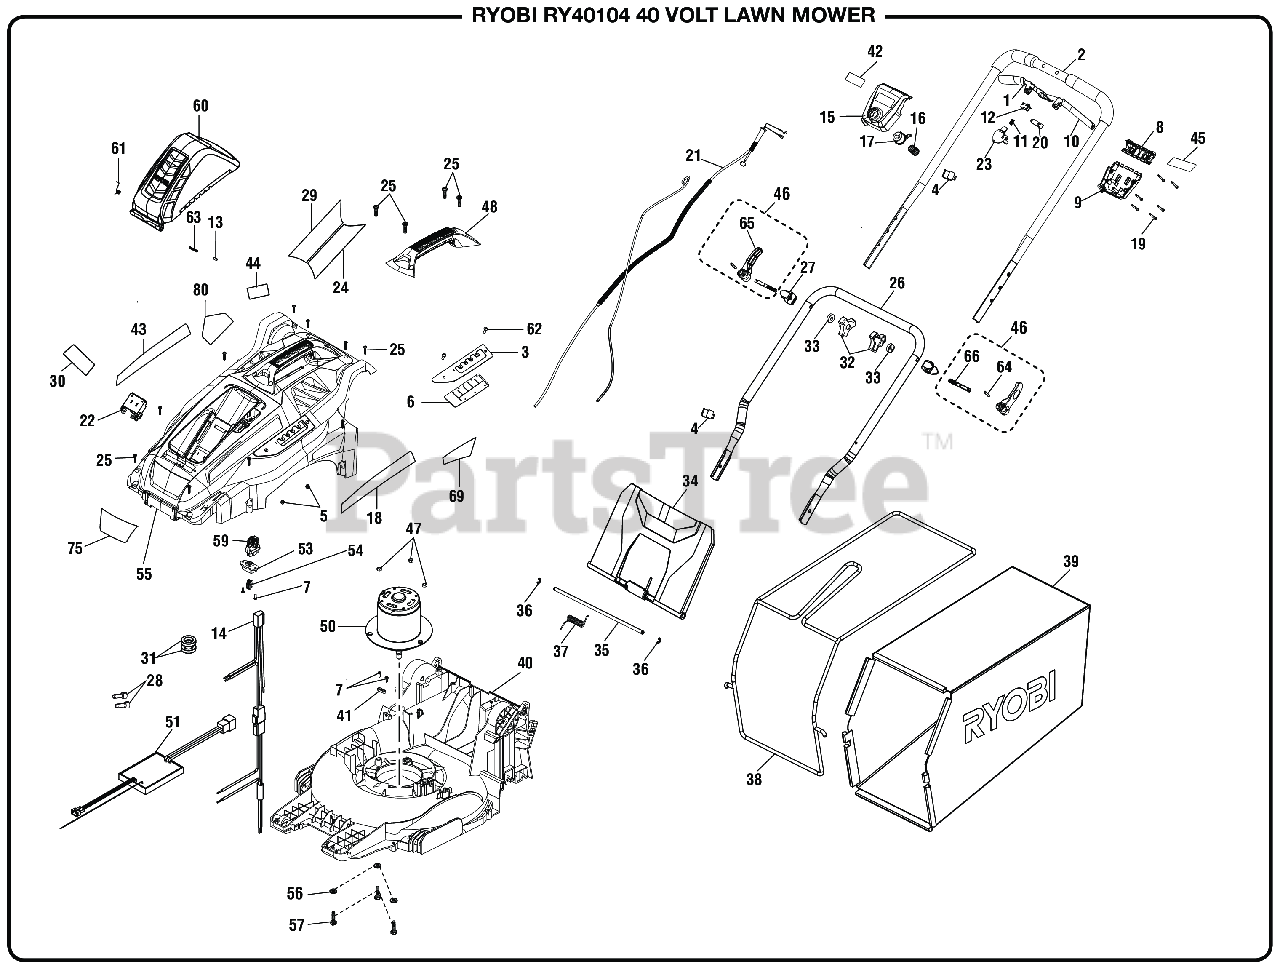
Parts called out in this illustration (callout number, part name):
1	Trigger Handle (Right Power Lever)
2	Upper Handle Assembly
3	Height Adjustment Plate
4	Cord Clamp
5	Lock Nut (M5 x 0.8 mm)
6	Dust Gasket
7	Screw (M4 x 16 mm, T20 Torx Pan Hd.).
8	Lower Cover (Stain Handle)
9	Lower Cover (Trigger Housing)
10	Trigger Handle (Left Power Lever)
11	Compression Spring
13	Battery Door Axle
14	Terminal Block w/Leads
15	Upper Cover (Control Assembly)
16	Handle Adjustment Spring
17	Safety Button
18	Lithium Label (Left)
19	Screw (M4-18 x 30 mm, T15 Torx Soc. Hd.)
21	Starter Cable (Long)
22	Battery Holder Assembly
23	Switch Holder
24	Warning Icon Label (Right)
25	Screw (M4 x 20 mm, T20 Torx Pan Hd. S.T.)
26	Lower Handle
27	Pressure Block
28	Wire Connector (Closed End)
29	Warning Icon Label (Left)
30	Start Key Label (Eng)
31	Ferrite Induct Ring
33	Block Washer
34	Rear Discharge Door
35	Rear Door Axle
36	Retaining Ring (E)
37	Torsion Spring (Rear Door)
38	Bag Frame
41	Wire Press Plate
42	Ryobi Logo Label (Handle)
43	Lithium Label (Right)
44	Data Label
45	Starting Instructions Label
46	Handle Lock Assembly
47	Lock Nut (M6)
51	Soft Start Circuit Board
53	Key Holder
54	Female Terminal
55	Deck Cover
56	Washer (ID6.2 x OD15 x 0.08t)
57	Bolt (M6 x 26 mm, Hex Hd.)
59	Start Key
60	Battery Cover
61	Torsion Spring (Battery Door)
62	SCREW (M5 x 16 mm SOC. WASHER HD. CAP)
63	Compression Spring
64	Spring Pin
65	Adjust Height Handle
66	Quick Lock Press
69	Cut Diameter Label (Left)
75	Ryobi Logo Label (Handle)
80	Danger Label (No Hands/Feet)
